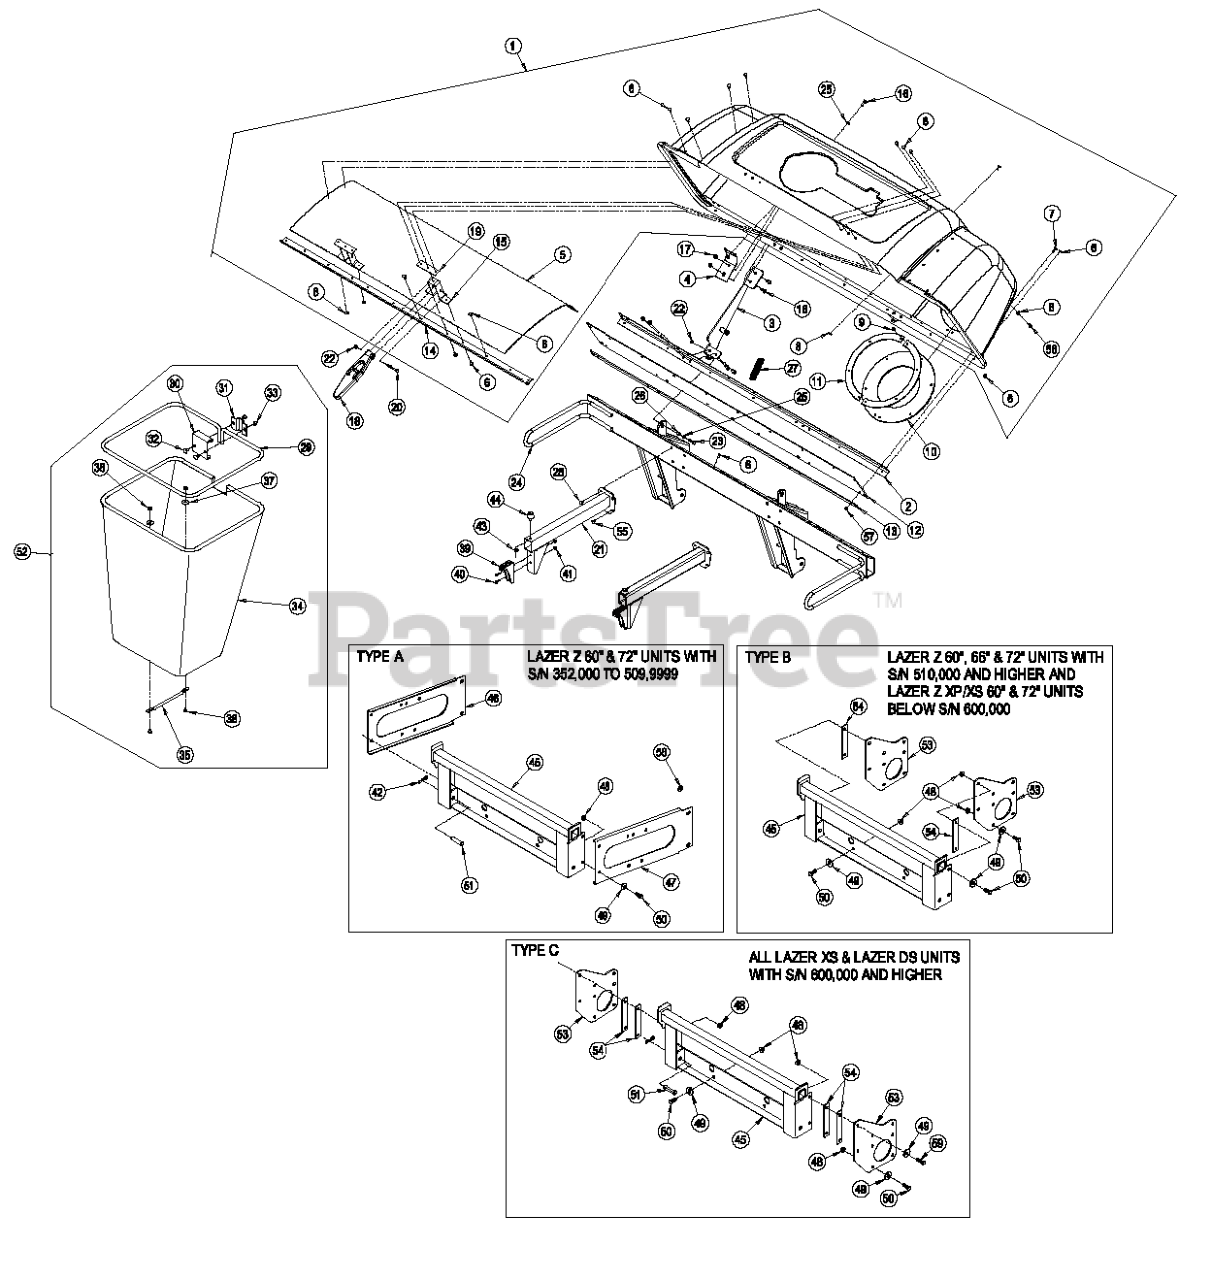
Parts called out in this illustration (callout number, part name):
1	ASM, HOOD
2	STIFFENER-BAGGER, TOP
3	HINGE ASM
4	REINFORCEMENT-HOOD, BAGGE
5	SCREEN-BAGGER
6	RIVET-BLIND
7	SCREW-HEAD, TRUSS
8	WASHER-FLAT
9	NUT-LOCK, NI
10	SEAL-TUBE
11	CLAMP-SEAL
12	SEAL-HINGE
13	PLATE-BACKING
14	SUPPORT-SCREEN
15	BRACKET-MOUNT
16	SCREW-HH
19	PLATE-LATCH, REINFORCEMEN
20	SCREW-HH
21	SUPPORT-BAG
22	NUT-LOCK, NI
23	SCREW-HH
24	UPRIGHT BAGGER ASM
25	WASHER-FLAT
27	SPRING-EXTENSION
28	SCREW-HH
29	FRAME-BAG
30	HANGER-BAG
32	BOLT-CARR
33	NUT-LOCK, NI
35	HANDLE-BAG
36	BOLT-CARR
38	NUT-LOCK, NI
40	SCREW-PPH
42	PIN-COTTER
45	MOUNT-BAGGER
46	BRACKET-FRAME, LH
47	BRACKET-FRAME, RH
48	NUT-HHF, WHIZ
49	WASHER-BELLEVILLE
50	SCREW-HH
51	PIN-CLEVIS
52	BAG AND FRAME ASM
53	PLATE-MOUNT, BAGGER
55	SCREW-HSBH
56	SCREW-PPH
57	NUT-LOCK, SIDE
58	SPACER
59	SCREW-HH
